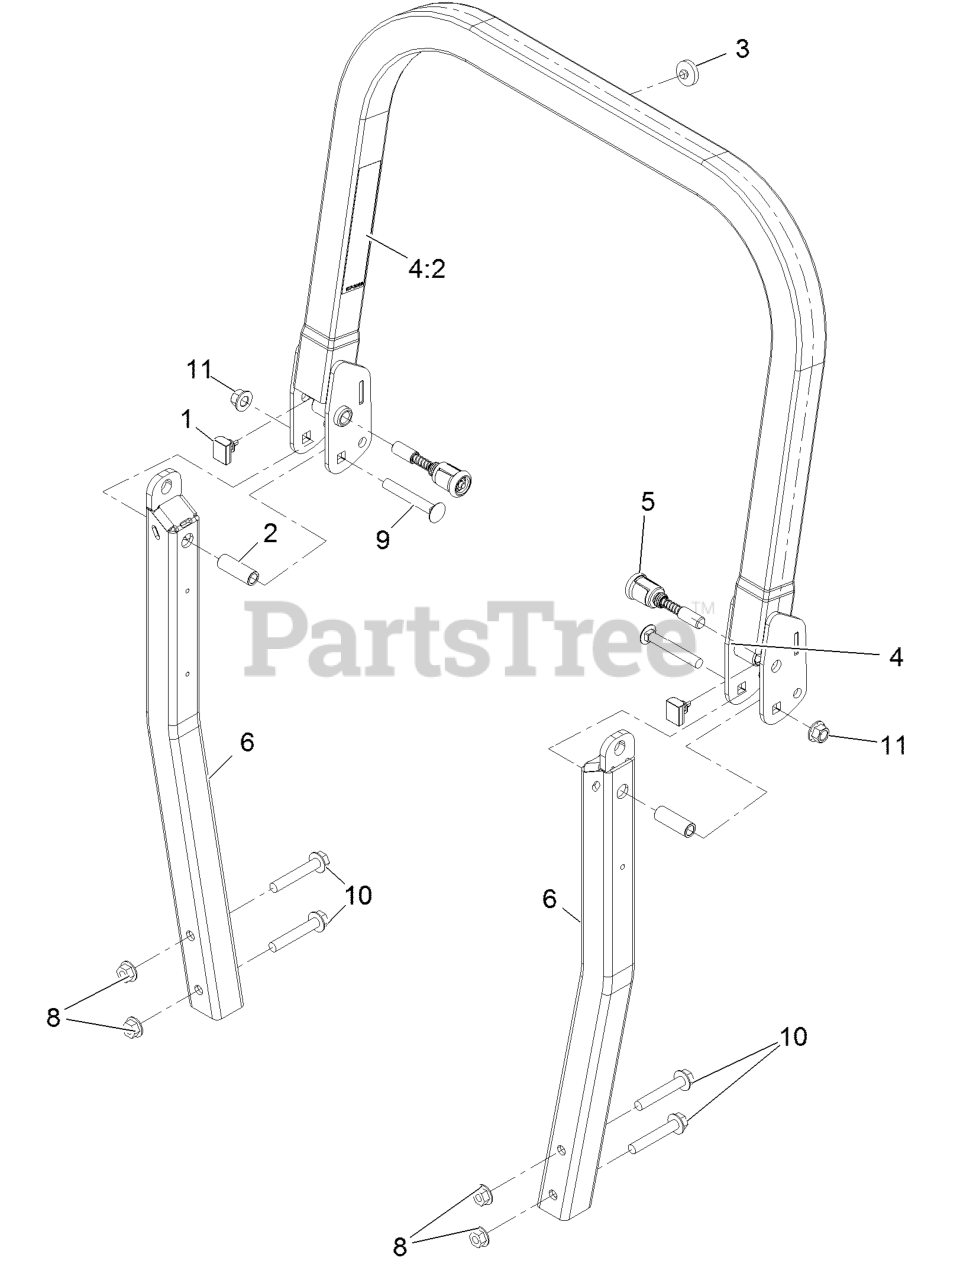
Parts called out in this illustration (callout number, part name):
1	BUMPER-ROPS
3	BUMPER-PUSH-IN, RUBBER
4	UPPER ROPS ASM
4:2	DECAL-WARNING
5	PIN-SPRING
6	ASM-Lwr ROPS Leg
8	NUT-HHF
9	SCREW-CARR
10	SCREW-HF
11	Nut-Lock 1/2-13
